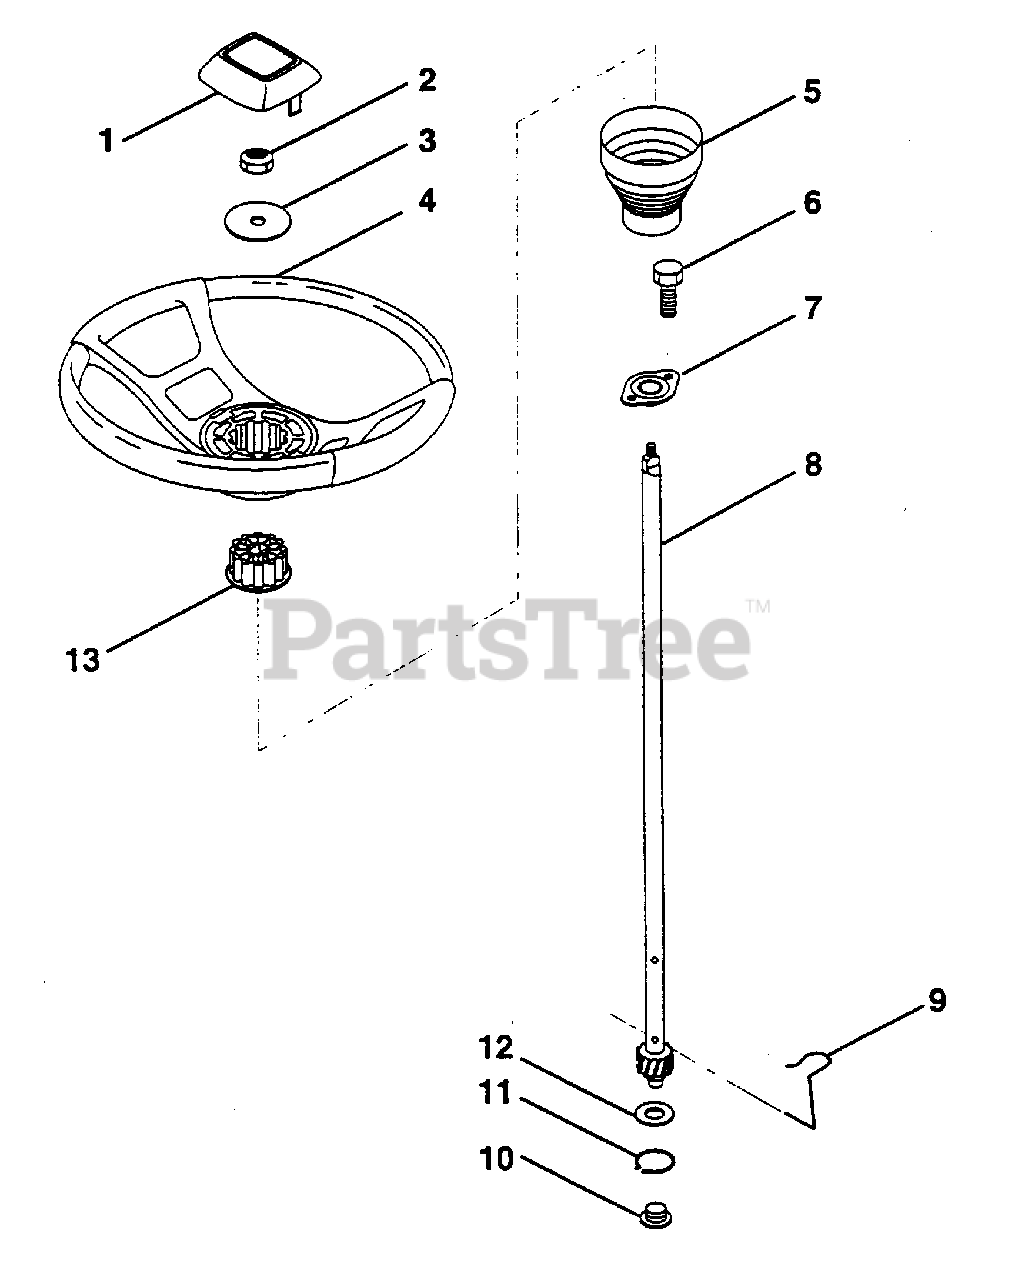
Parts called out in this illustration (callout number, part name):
1	Insert, Wheel, Steering
2	Locknut 3/8-24 UNF
3	Washer 12/32 x 2-3/8 x 8 Ga.
4	Wheel, Steering
5	Sleeve, Steering
6	Screw, Hex #10-16 x 1/2 TY-B
7	Bushing, Steering
8	Shaft, Steering
9	Clip, Steering
10	Bushing, Lower, Steering
11	Ring, Retaining
12	Washer 21/32 x 1 x 16 Ga.
13	Adaptor, Wheel, Steering
